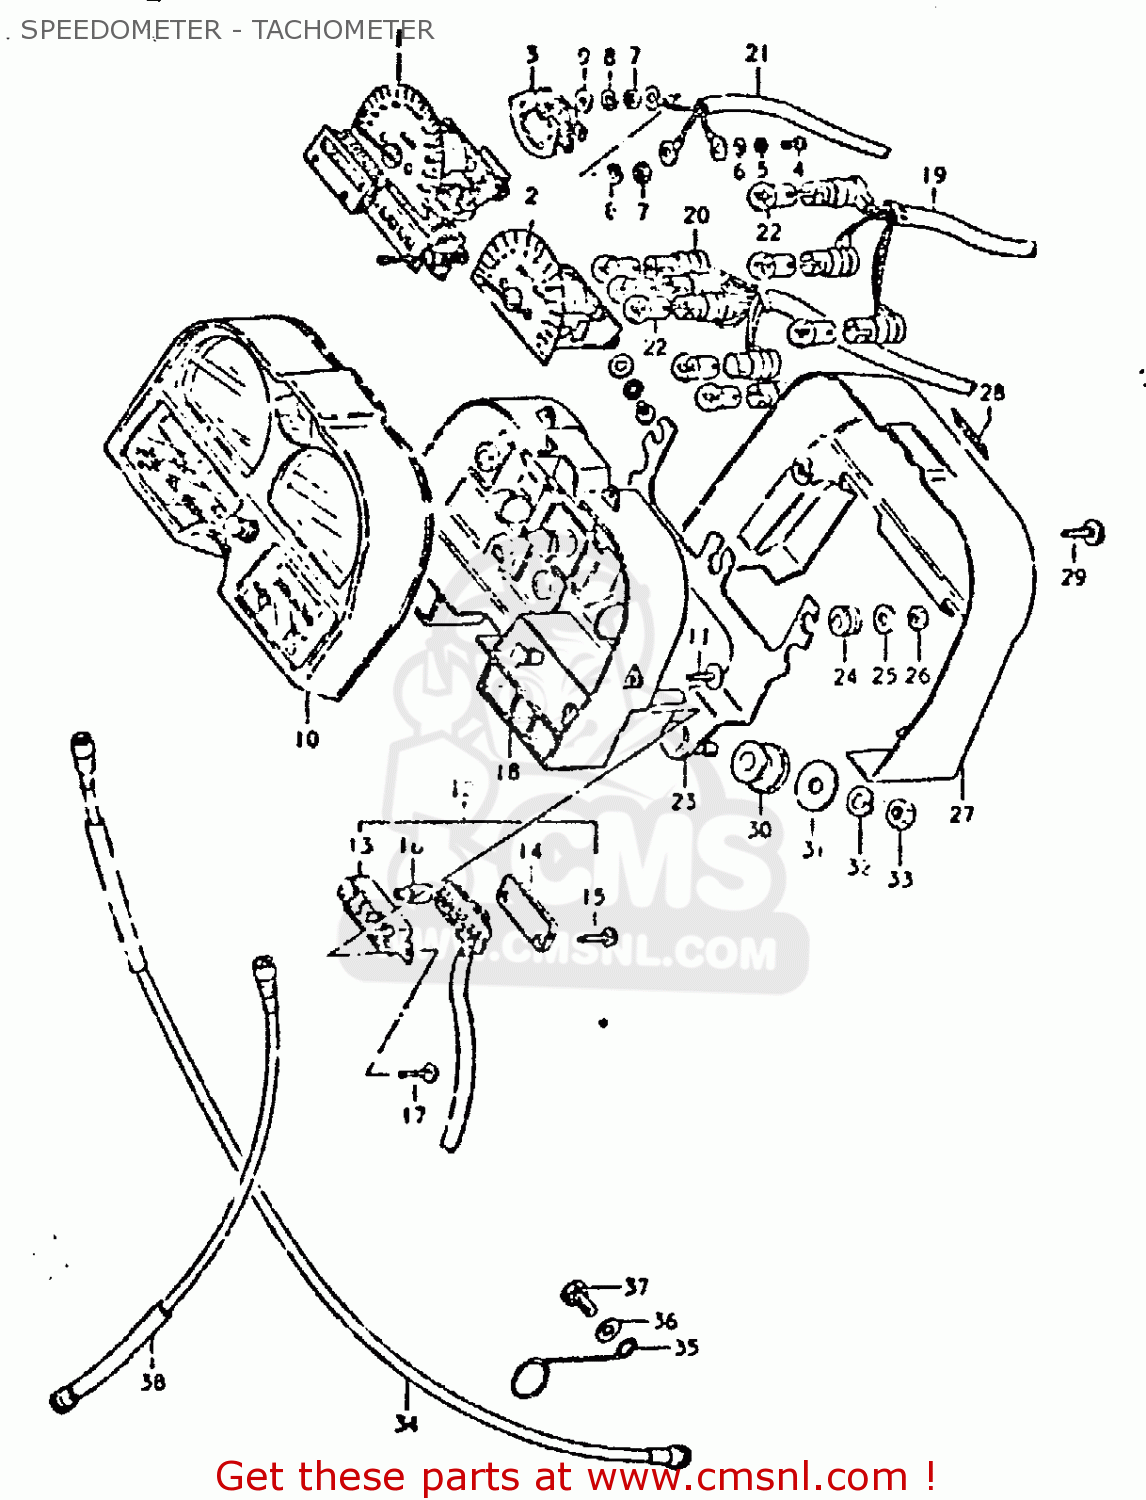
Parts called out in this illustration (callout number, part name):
1	SPEEDOMETER
2	METER,TACHOMETER
3	METER,FUEL
4	SCREW 3X12
5	LOCK WASHER
6	WASHER
7	NUT 4MM
8	LOCK WASHER
9	WASHER
10	HOOD,METER
11	SCREW
12	INDICATOR ASSEMBLY,GEAR POSITION
13	CASE,GEAR INDICATOR
14	COVER,LWR
15	SCREW,GEAR INDICATOR
16	BULB(14V1.12W)
17	SCREW
18	CASE,COMBINATION METER
19	SOCKET,METER
20	SOCKET
21	LEAD WIRE,FUEL METER
22	BULB(12V3.4W,STANLEY,A72A)
23	BRACKET,METER
24	CUSHION,METER
25	WASHER,METER
26	NUT
27	COVER,METER,UNDER
28	EMBLEM
29	SCREW
30	CUSHION,METER BRACKET
31	WASHER (8.5X29X1.6)
32	LOCK WASHER
33	NUT
34	CABLE ASSEMBLY,SPEEDOMETER
35	GUIDE,SPEEDOMETER CABLE
36	WASHER
37	BOLT, UPPER
38	CABLE ASSEMBLY,TACHOMETER
